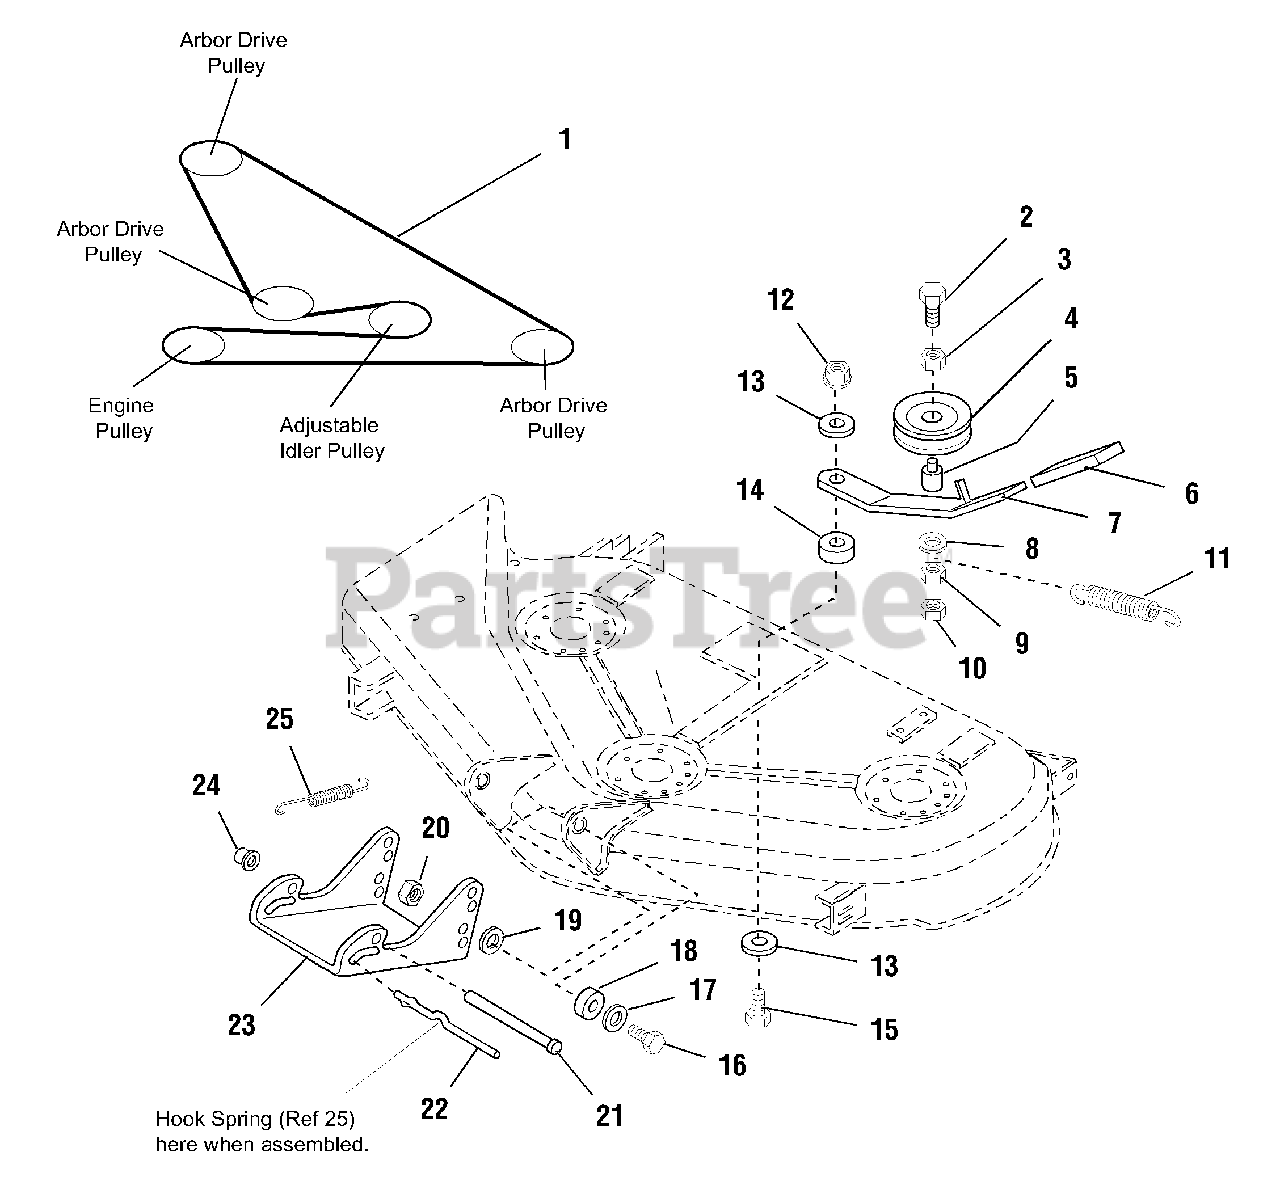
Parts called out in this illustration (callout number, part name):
2	CAPSCREW, Hex Hd., 3/8-16 x 2-1/4"
3	WASHER, 3/8
4	PULLEY ASSEMBLY
5	HUB, Insert
6	GRIP, Lever
8	LOCKWASHER, Spring, 3/8
9	NUT, Hex, 3/8-16
10	NUT, Hex Flange Lock, 3/8-16
12	NUT, Hex, Center Lock, 3/8-16
13	WASHER
14	SPACER, Idler Arm
15	CAPSCREW, 3/8-16 x 1-1/4"
16	CAPSCREW, Hex, 3/8-16 x 1-1/2
17	WASHER, 3/8
20	NUT, Hex Lock, 3/8-16
21	ROD, Mower Hitch
24	NUT, Push, 1/2
25	SPRING
